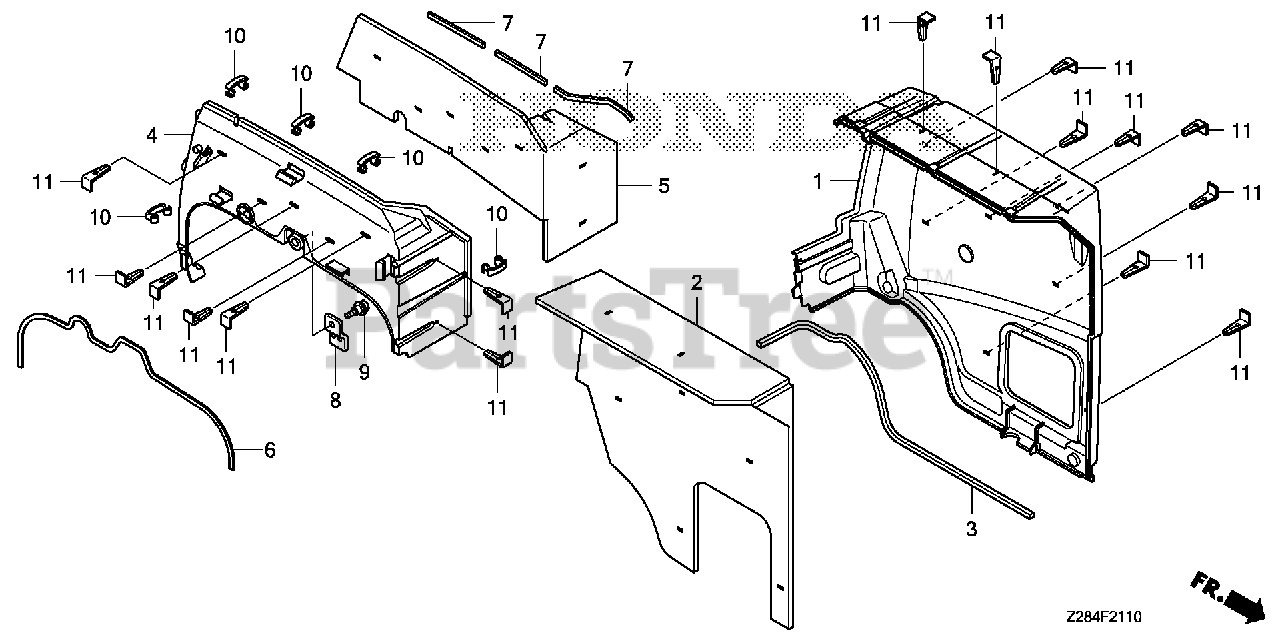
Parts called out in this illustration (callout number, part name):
1	SHROUD, R.
2	INSULATOR, R. SHROUD
3	SEAL, R. SHROUD
4	SHROUD, L.
5	INSULATOR, L. SHROUD
6	SEAL, L. SHROUD
7	SEAL A, L. SHROUD
8	BRACKET, STOPPER
9	BOLT, SPECIAL (6MM)
10	CLAMP, CASE
11	CLIP, INSULATOR BIND (A)
